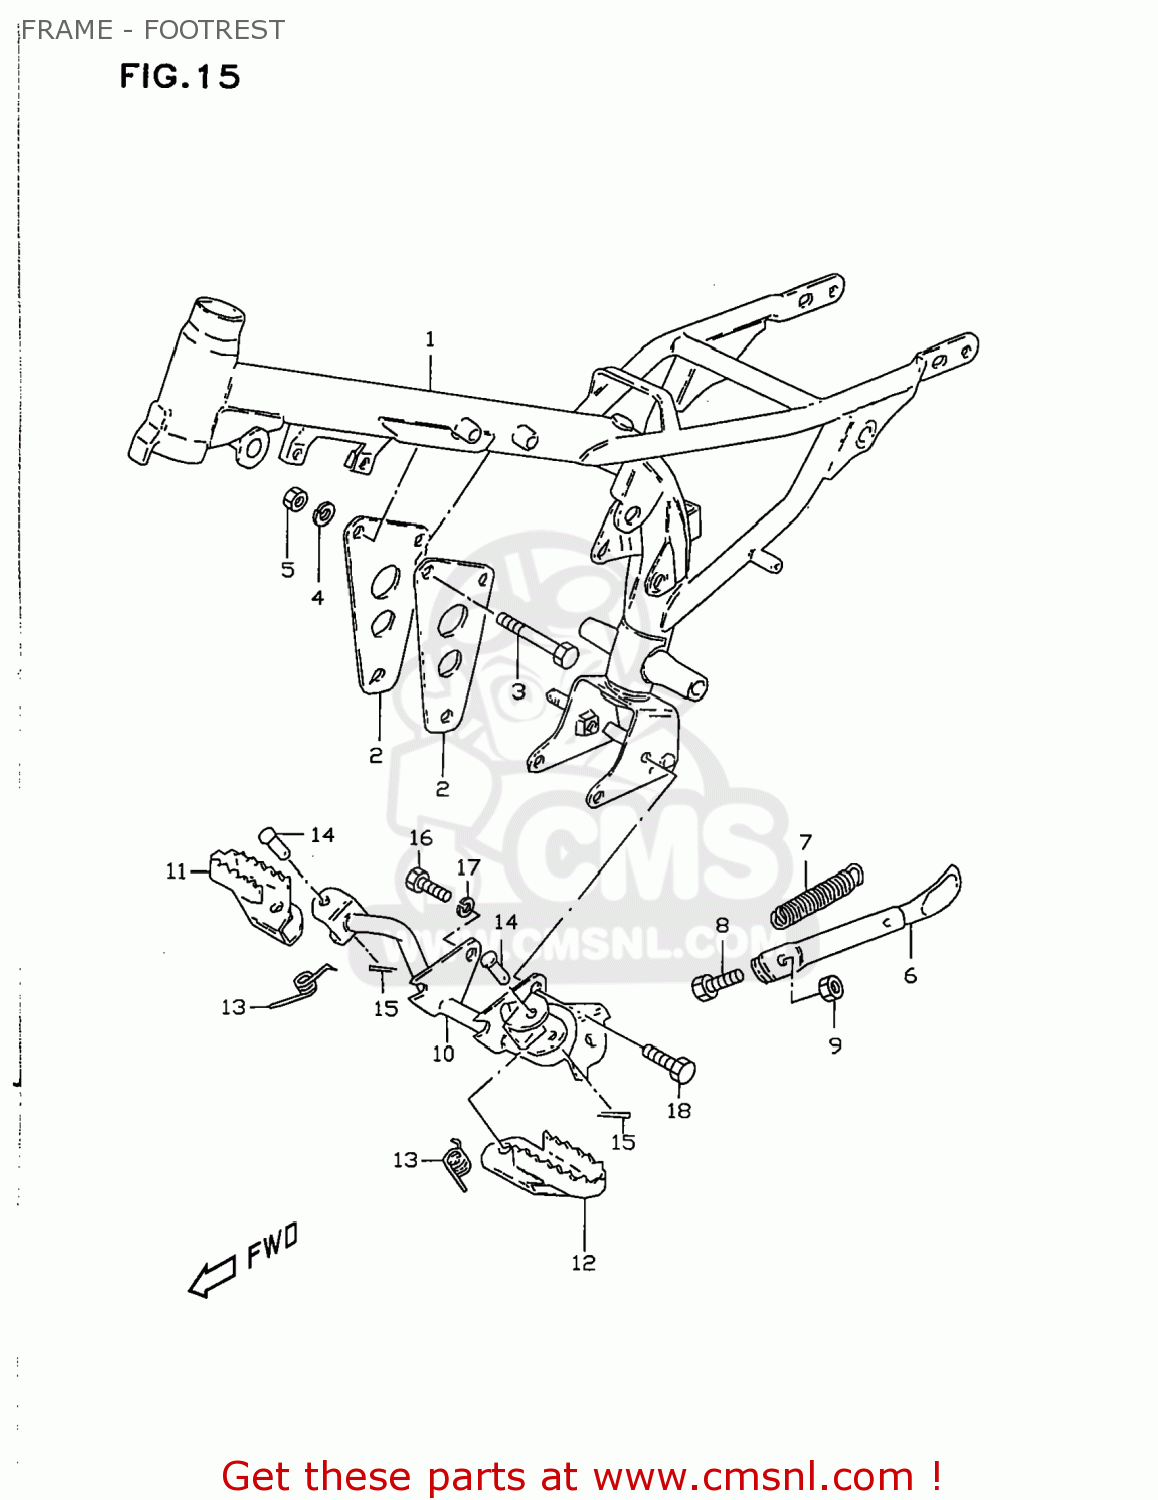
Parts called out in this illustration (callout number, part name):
1	FRAME (BLACK)
2	PLATE,ENG MTG
3	BOLT
4	LOCK WASHER
5	NUT
6	STAND,PROP
7	SPRING
8	BOLT 8X22
9	NUT
10	BAR,FR FOOTREST
11	FOOTREST,FR,R
12	FOOTREST,FR,L
13	SPRING
14	PIN
15	PIN
16	BOLT
17	LOCK WASHER
18	BOLT(8X14)
